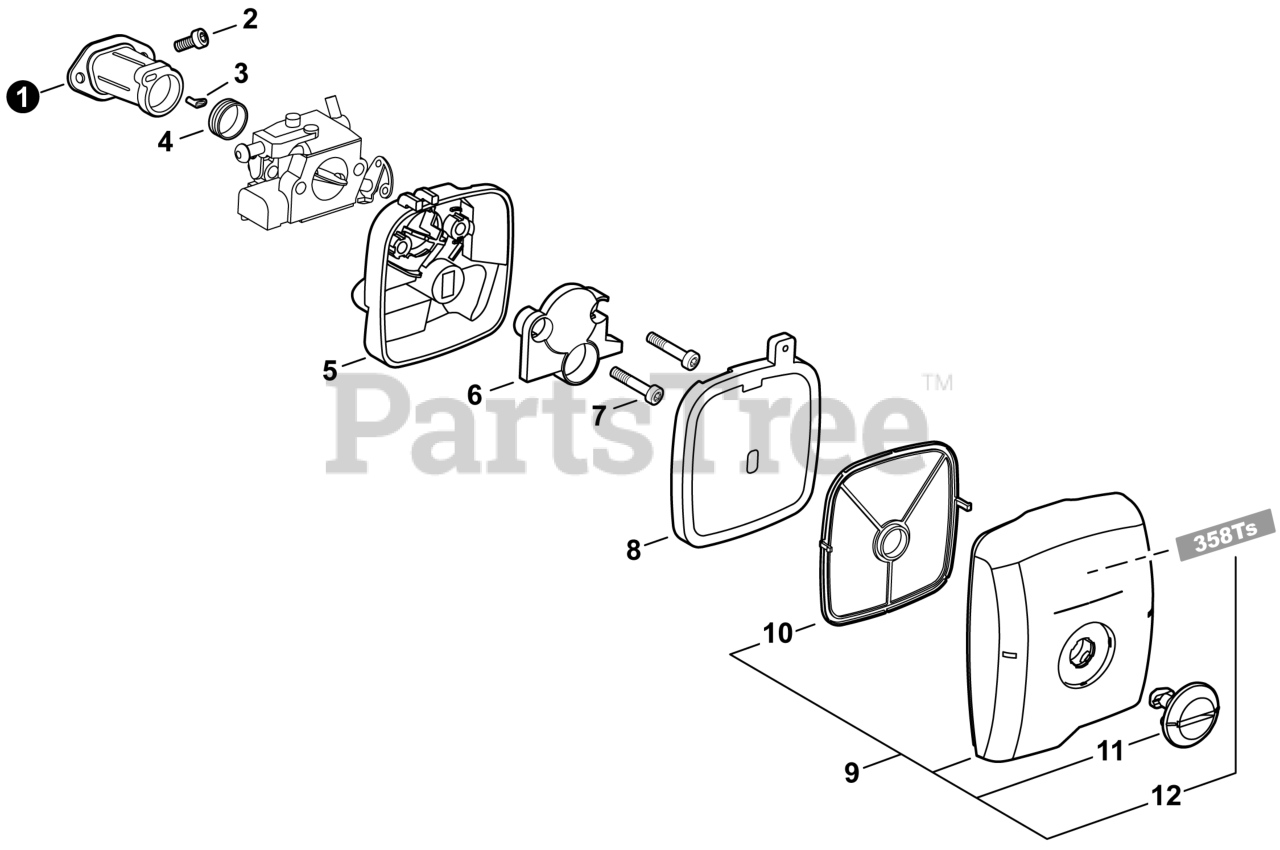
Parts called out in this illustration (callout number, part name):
1	BELLOWS, INTAKE
2	BOLT, TORX 5x12
3	COLLAR 3.2x6.5
4	SPRING, TENSION
5	CASE, AIR FILTER
6	PLATE, PREVENT
7	BOLT, TORX 5x50
8	FILTER, AIR - FELT
9	COVER ASSY, AIR FILTER
10	SEAL, AIR FILTER
11	KNOB, AIR FILTER COVER
12	LABEL - MODEL
